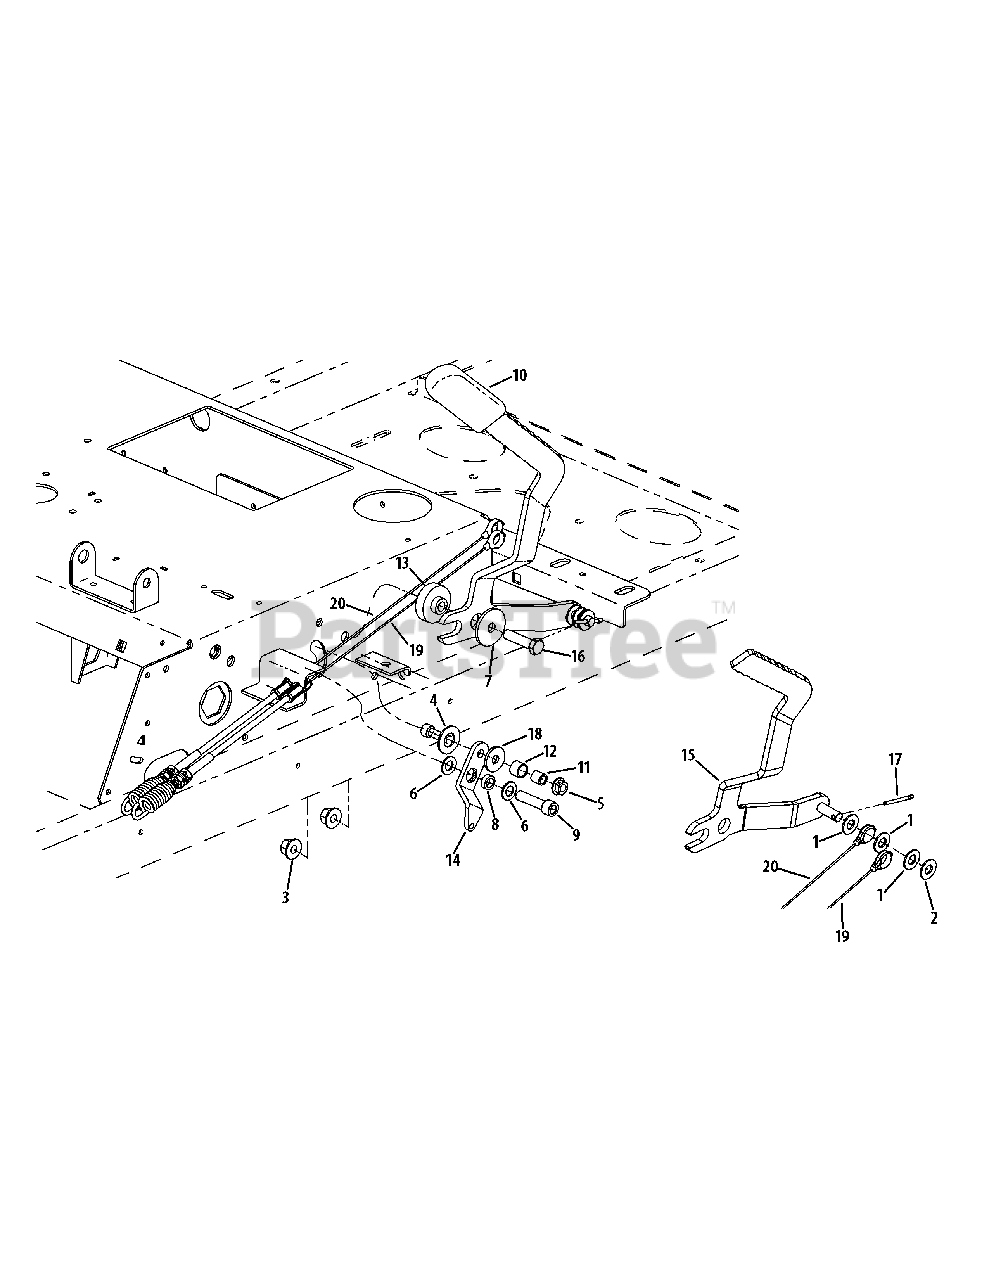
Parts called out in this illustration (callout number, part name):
1	Flat Washer, .406 x .812 x .062
2	Flat Washer,3/8
3	Hex Nut,3/8-16 Flange Lock
4	Slide Washer
5	Flange Lock Nut,5/16-18
6	Washer, .375 x .738 x .063
7	Flat Washer, .390 x 1.5 x .134
8	Spacer, .380 x .563 x .196
9	Socket Head Cap Screw, 3/8-16 x 1.50
10	Parking Brake Grip
11	Spacer, .322 x .438 x .44
12	Spacer, .442 x .563 x .405
13	Step Hub, .379 x 1.5 x .257/.400
14	Lockout Lever Plate
15	Brake Handle
16	Hex Head Cap Screw,3/8-16 x 1.50
17	Cotter Pin, 1/8 x .75
18	Washer, .345 x 1.00 x .100
19	Left Hand Brake Cable
20	Right Hand Brake Cable
